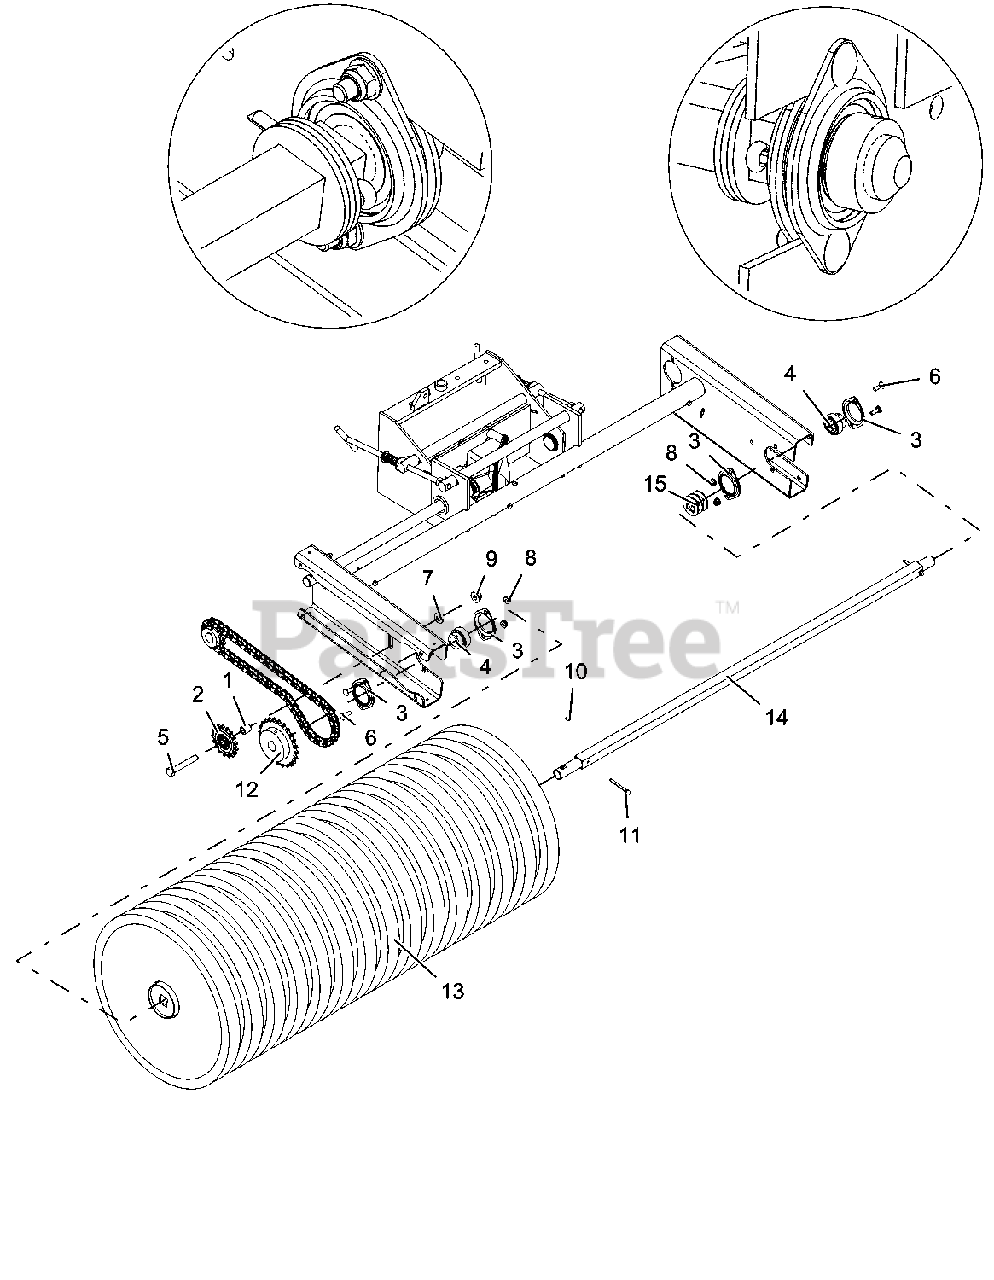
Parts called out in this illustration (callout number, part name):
1	SPACER .510X.750X.750
2	SPROCKET, 17 TOOTH NO 50 CHAIN
3	MTG-FLG 2 HOLE 52MM X 3.75
4	BRG/W COLLAR 1.0 X 2.047 X.844
5	BLT,HEX .50-13X3.25 G5ZC120
6	BLT,RHSN .31-18X1.00 G5 ZC120
7	WSHR,FL-STL.531X1.06X.095ZC120
8	NUT,LK-NYL-FLG .31-18 G5ZC120
9	NUT,LK-NYL-FLG .50-13 G5ZC120
10	KEY-WDRF .25X.750X.313 SAE91
11	PIN,CTR.25X2.00EXTPRSQCT ZC120
13	BRUSH,44IN
14	SHFT,POWER BRUSH
15	SPCR, SQ 1.010X2.000X.125
